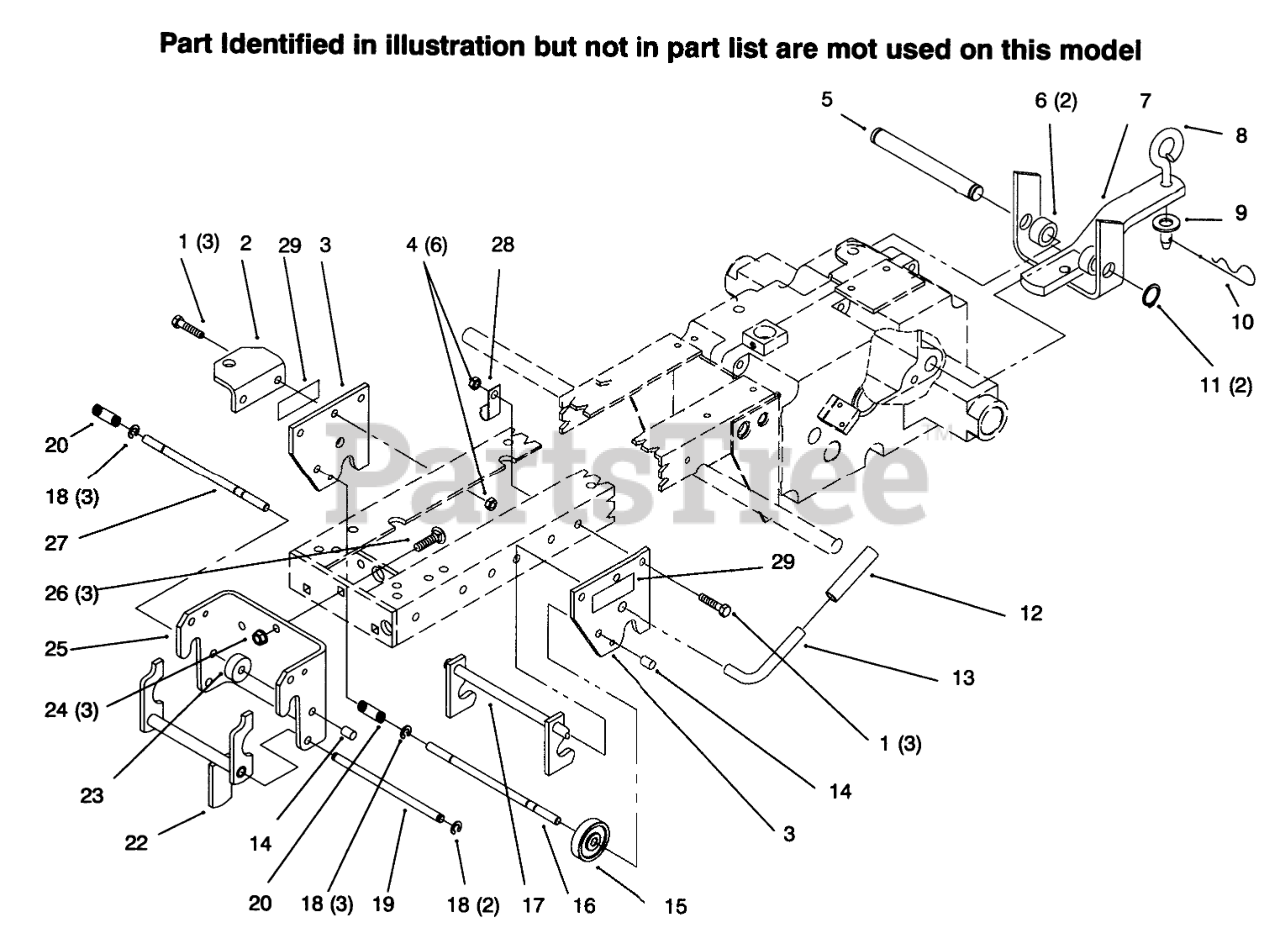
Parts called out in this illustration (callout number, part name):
1	SCREW-HH
2	Axle
3	Hitch Plate
4	NUT-LOCK, NI
5	PIN-STATIONARY HITCH
6	SPACER
7	Hitch
8	PIN-TOOL
9	WASHER-FLAT
10	PIN-HAIR
11	E-RING
12	GRIP
14	CAP-ROD, PLUNGER
16	ROD-LOCK
17	MID HITCH ASM
18	RING-RETAINING
19	ROD-LATCH PIVOT
20	SPRING
22	LATCH
24	NUT-LOCK, NI
25	Front Hitch
26	BOLT-CARR
27	ROD-LOCK
28	CLIP
29	DECAL - ATTACH-A-MATIC
